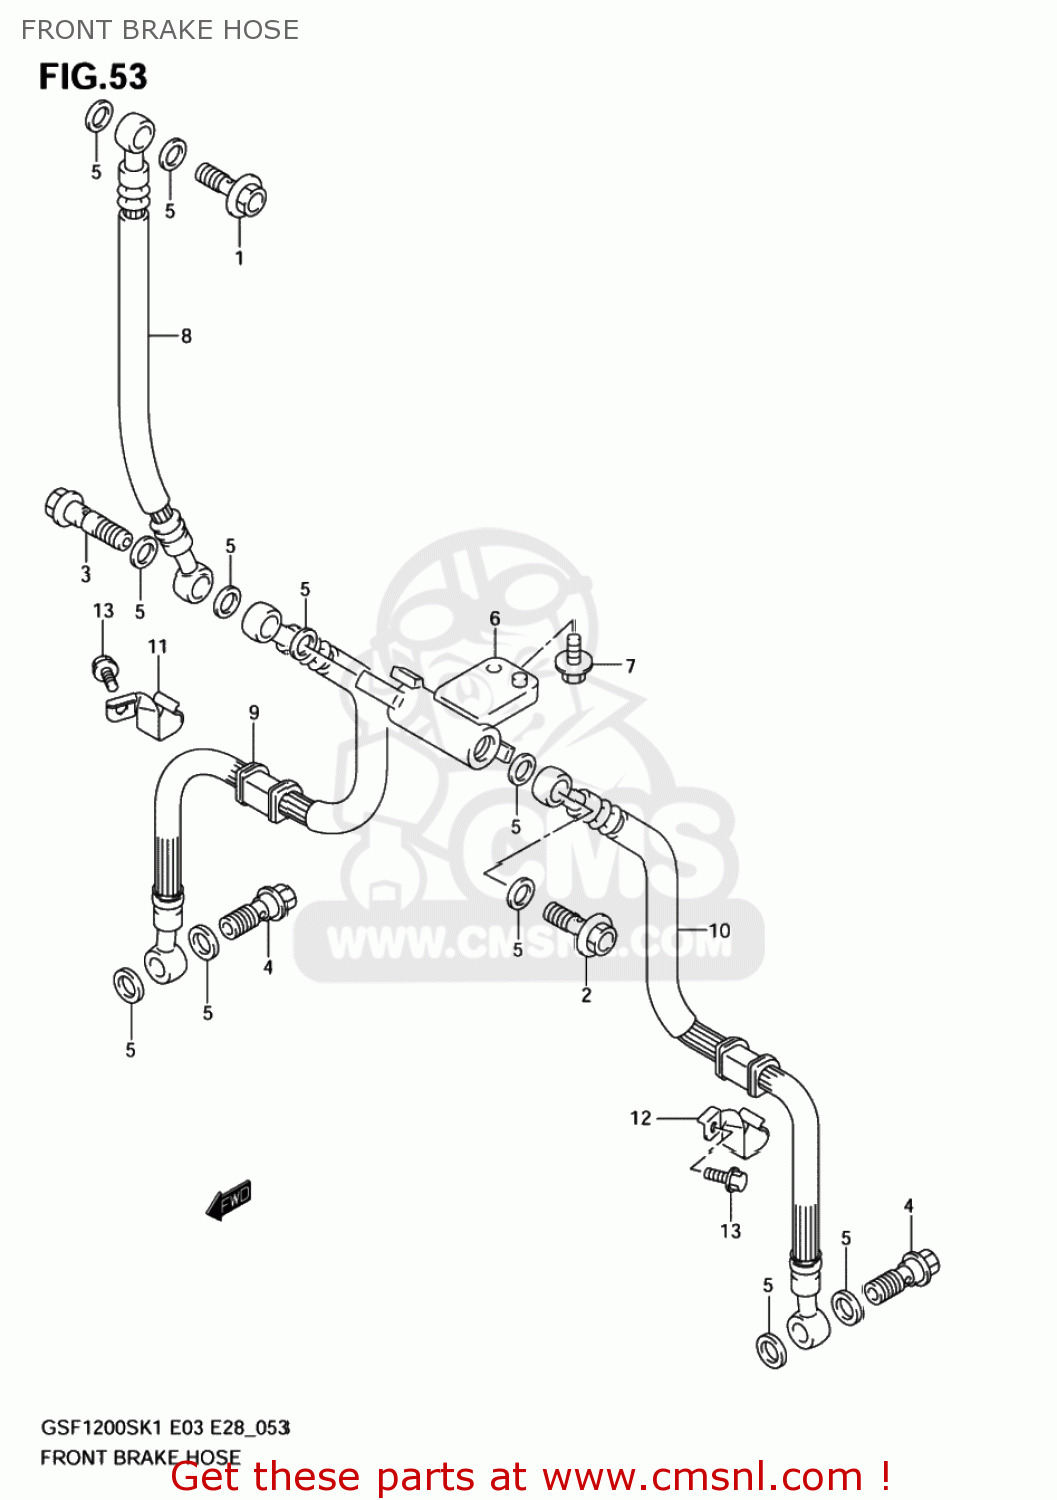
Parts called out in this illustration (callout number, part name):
1	BOLT UNION
2	BOLT UNION
3	BOLT UNION
4	BOLT UNION
5	WASHER(10X15X1.5)
6	JOINT,BRAKE HOSE
7	BOLT
8	HOSE,FR BRAKE NO.1
9	HOSE,FR BRAKE NO.2,R
10	HOSE, FRONT BRAKE NO.2 LH
11	CLAMP,FR BRAKE HOSE NO.2,R
12	CLAMP,FR BRAKE HOSE NO.2,L
13	BOLT
